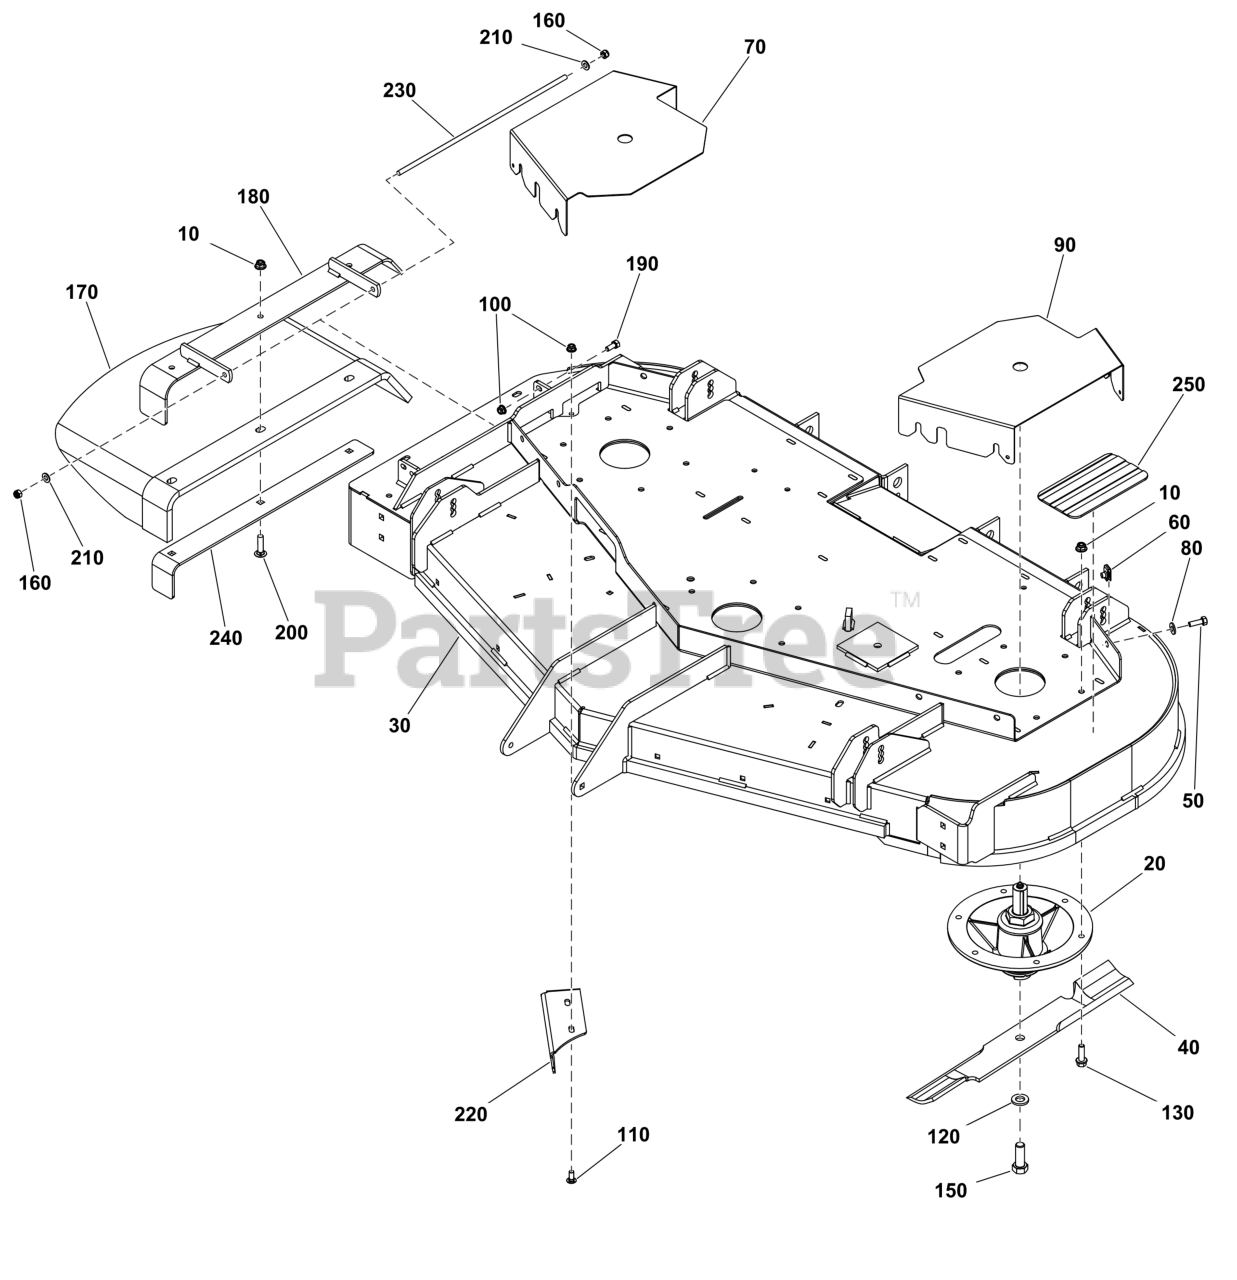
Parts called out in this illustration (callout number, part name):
10	NUT, 3/8-16 HEX NYLOCK
20	SPINDLE ASSEMBLY
30	DECK SHELL W/DECALS, 60" (5423418B)
40	BLADE SET, 61 DECK (3)
60	BODY CLIP, 5/16-18 X
70	GUARD, RH
80	WASHER, 5/16" GD.9 FL
90	GUARD, LH
100	NUT
110	BOLT, 5/16-18 X 3/4",
120	WASHER, 5/8" YZ
130	BOLT
150	BOLT
160	NUT, 5/16-24 HEX NYLO
170	CHUTE, RUBBER DISCHARGE (5104442)
180	FRAME, Chute
190	BOLT, 5/16-18 X 3/4"
200	BOLT, 3/8-16 X 1-1/2
210	WASHER
220	DEFLECTOR
230	ROD
240	PLATE, SUPPORT
250	SAFETY WALK
